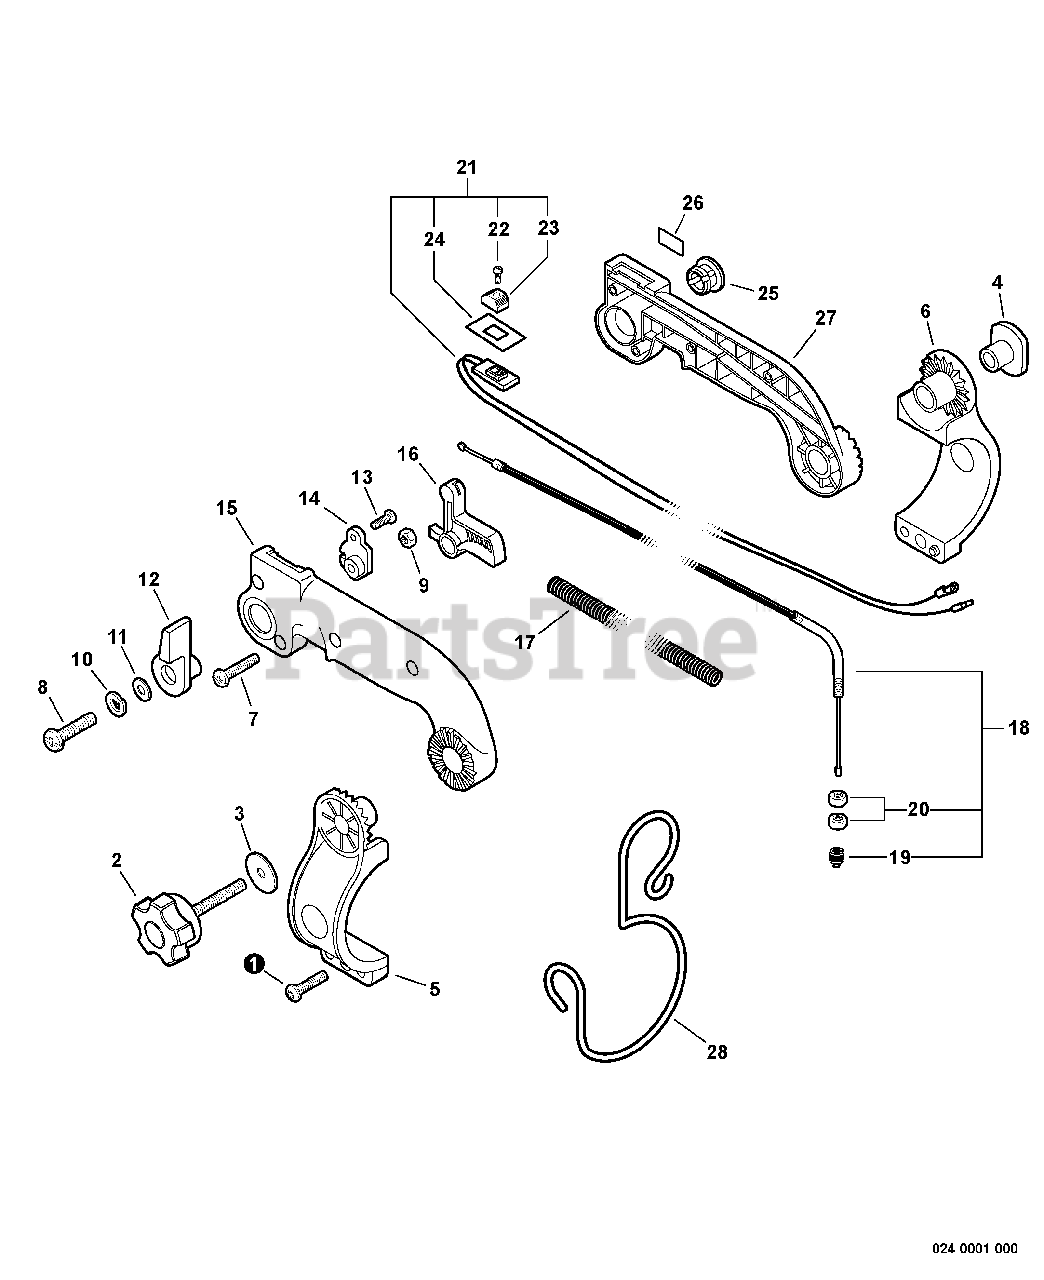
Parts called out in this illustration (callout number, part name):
1	SCREW - 5X20 -- TAPPING
2	THUMBSCREW
3	WASHER - 6
5	BRACKET, HANDLE - LEFT
6	BRACKET, HANDLE - RIGHT
7	SCREW - 4X22
8	SCREW - 6X20
9	LOCKNUT - 6
10	LOCKWASHER - 6
11	WASHER - 6
12	CONTROL, THROTTLE
13	SCREW - 4X10
14	BRACKET, THROTTLE
15	HANDLE, CONTROL - LEFT
16	TRIGGER, THROTTLE
17	TUBE, PROTECTIVE - CORRUGATED
18	THROTTLE CABLE ASSY
19	CAP, DUST
21	SWITCH, IGNITION
22	SCREW - 3X10
23	KNOB, SWITCH - ORANGE
24	COVER, SWITCH - STOP
26	LABEL - STOP
27	HANDLE, CONTROL - RIGHT
